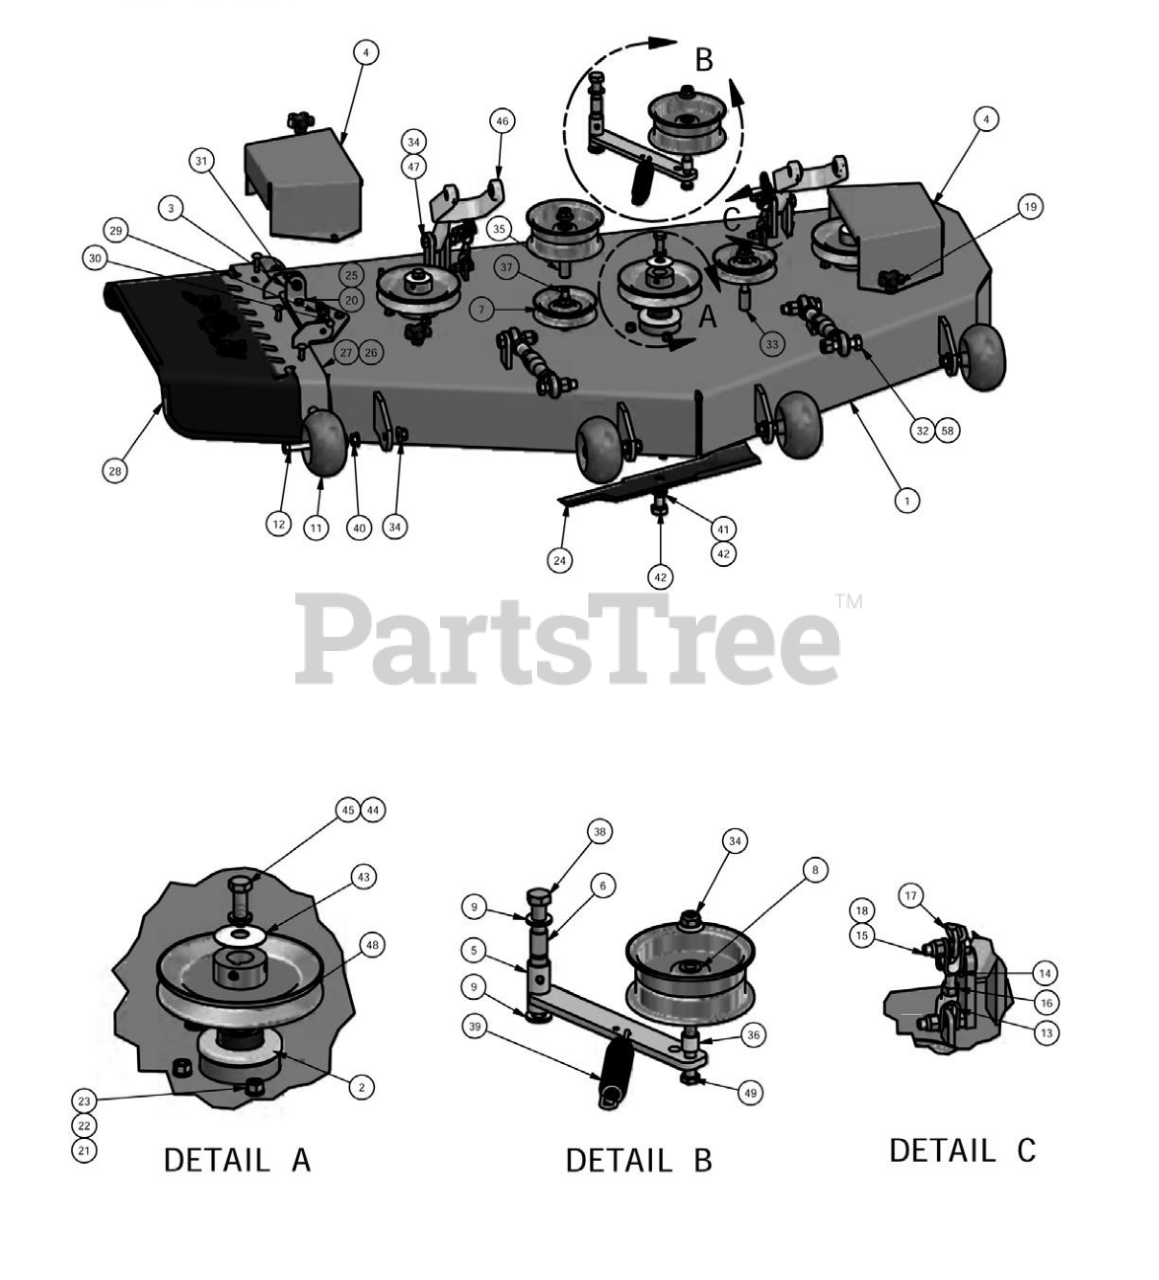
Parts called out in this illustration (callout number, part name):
1	52" Deck Shell
1A	52" Deck Assembly
2	Double Bearing Spindle (Complete)
3	Discharge Chute Hanger
4	Pulley Cover
5	Deck Idler 2009
6	5/8" ID x 1 1/8" Brass Bushing
7	4 3/4" Idler Pulley
8	5 3/4" Deck Idler Pulley
9	.635 ID Plastic Washer
10	Turnbuckle (Top Link)
11	Anti-Scalp Rollers
11A	Deck Wheel Assembly
12	1/2" x 4" Bolt (Grade 8)
13	Female Yoke
15	3/8" x 1 1/2" Hex Bolt
16	3/8" Hex Nut
17	3" Chain Assembly
18	3/8 Nylock Nut
20	3/8" x 3/4" Hex Bolt
21	3/8 x 1 1/4 Bolt
22	3/8" Lock Washer
23	3/8" Hex Nut
24	52" Fusion Blade
25	3/8" Flange Nut
26	48" Lower Hanger
27	48" Upper Hanger Plate
28	Rubber Discharge Chute
29	.360 ID Plastic Washer
30	5/16" x 1" Hex Bolt
31	5/8 Nylock Nut
32	5/8" x 2 1/2" Hex Bolt
33	Pup Pulley Spacer
34	1/2-13 Nylon Flange Nut-Orange
35	1 3/4" Pulley Spacer
36	3/4 OD x 1/2 ID x 3\4 Length
37	1/2 x 3 1/2 Flange Bolt
38	5/8" x 4" Hex Bolt
39	Deck Idler Spring 2009
40	1/2" Flange Nut
41	5/8" Lock Washer
42	5/8 x 1 1/2" Grade 8 Bolt
43	Cup Washer
44	1/2" Lock Washer
45	1/2" x 1 1/2" Fine Thread Bolt
46	Deck Arm Assembly
47	1/2" x 2 1/2" Hex Bolt
48	5" Deck Pulley
49	1/2 x 3" Bolt
58	5/8 Std NC Nylock Nut
